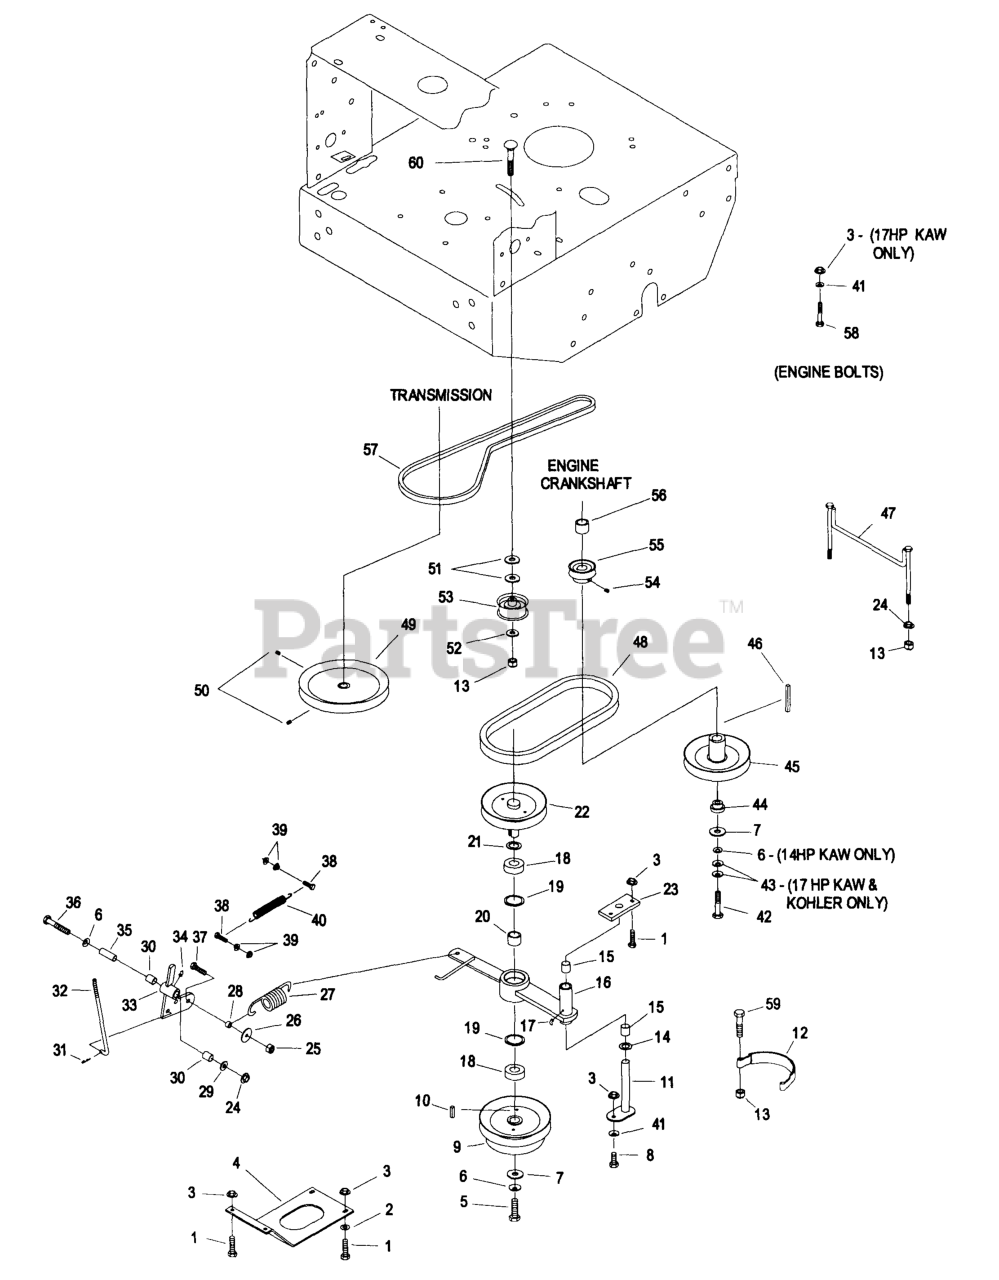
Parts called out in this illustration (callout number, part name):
4	PLATE-GUARD
5	SCRW,CAP HH
9	SHEAVE,6.13 W/HUB
11	WLD,PIN PIVOT
12	BAND,BRAKE BLADE
14	WASHER-SPACER
15	SLEEVE,BEARING
17	1481
18	BEARING,CLUTCH SHAFT
20	SPACER,CLUTCH BEARING
21	WASHER-SPACER
22	SHEAVE,6.13 W/SHAFT
23	PLATE-CLUTCH PIVOT
27	SPRING,BELT TENSION
28	SPACER,CLUTCH ANCHOR
30	SLEEVE-BEARING
31	PIN-COTTER
32	LINKAGE,LOWER
33	ASM,PIVOT W/BUSHINGS
35	BUSHING
40	SPRING,EXTENSION
41	WASHER-SPRING
42	SCRW,CAP HH
43	WASHER-SPRING
44	BUSHING,CLUTCH KEEPER
45	SHEAVE,ENGINE
46	KEY,MACH 1/4X1/4X2-5/8
47	GUIDE - BELT
48	BELT,BLADE CLUTCH
49	SHEAVE-TRANSMISSION
54	SCREW-SET
55	SHEAVE-TRANSMISSION
56	SPACER,CRANKSHAFT
57	BELT,TRANS DRIVE
